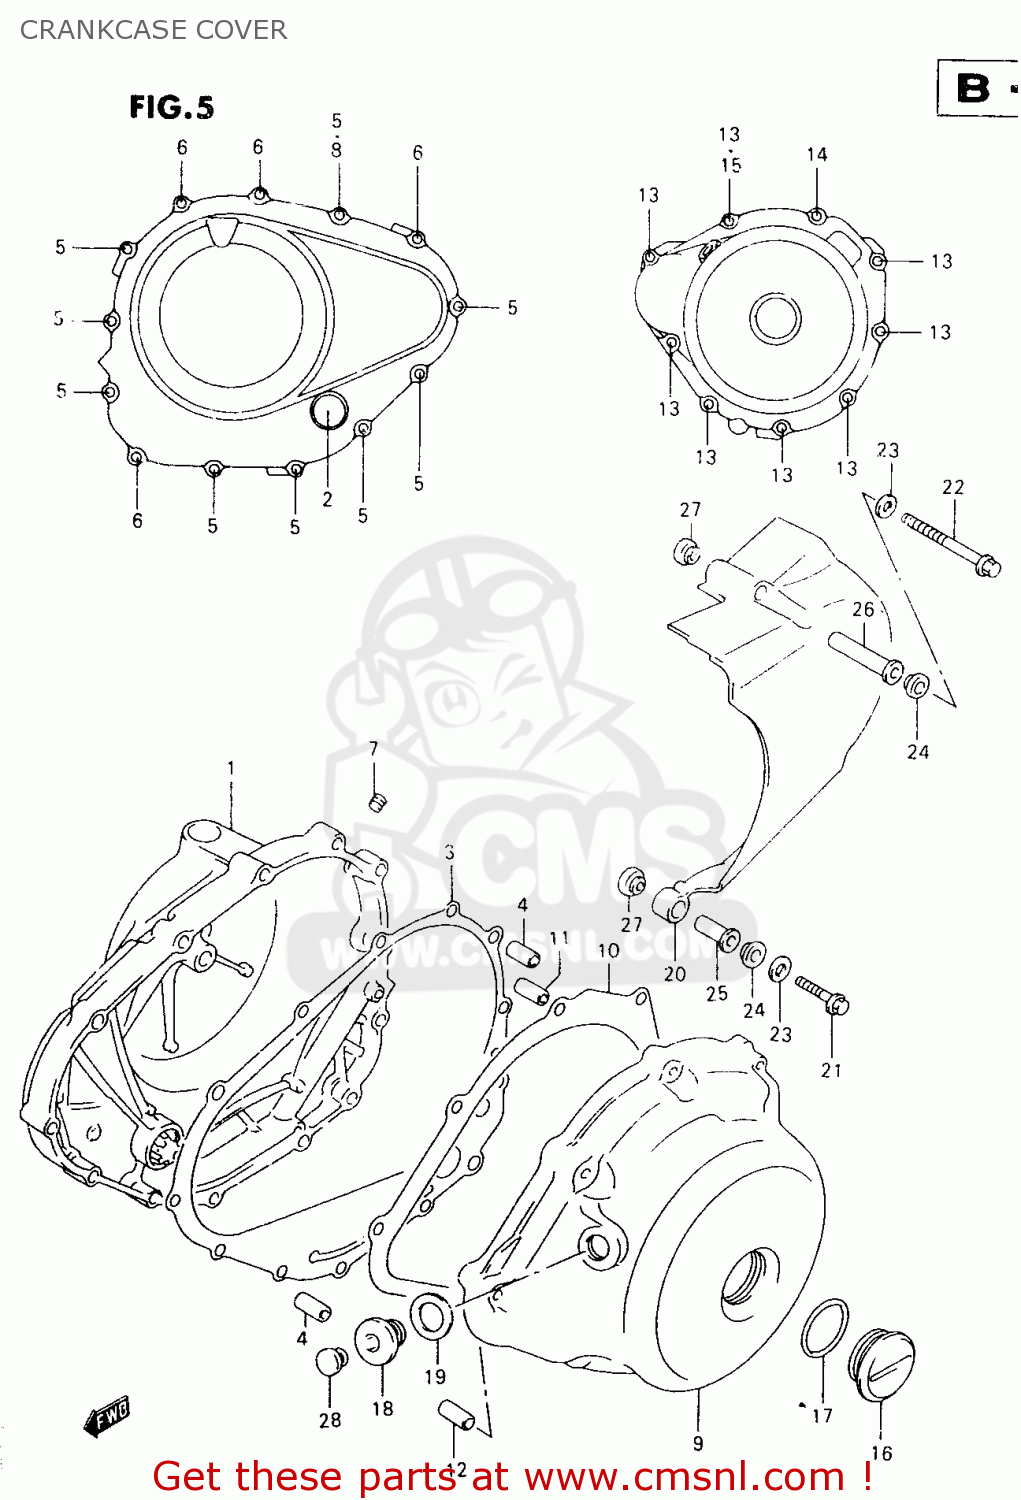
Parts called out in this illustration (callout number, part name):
1	COVER,CLUTCH
2	LENS,OIL LEVEL CHECK
3	GASKET,CLUTCH COVER
4	PIN
5	BOLT
6	BOLT
7	PLUG(1/8PT,H:5.5)
8	GASKET(5.8X11X1.2) (NAS)
9	COVER,MAGNETO
10	GASKET,CLUTCH COVER
11	PIN(8.4X11X20)
12	PIN
13	BOLT
14	BOLT
15	GASKET(5.8X11X1.2) (NAS)
16	Chrome Crankshaft Plug
17	O RING(D:3.1,ID:32.7)
18	PLUG,14X12
19	GASKET(13.8X18.8X4.8) (NAS)
20	COVER,ENGINE SPROCKET
21	BOLT
22	BOLT
23	WASHER
24	WASHER(8.7X15X2.1)
25	SPACER(6.5X9X19.4)
26	SPACER(6.5X9X47.1)
27	WASHER(8.7X16X5)
28	CAP(OD:12)
